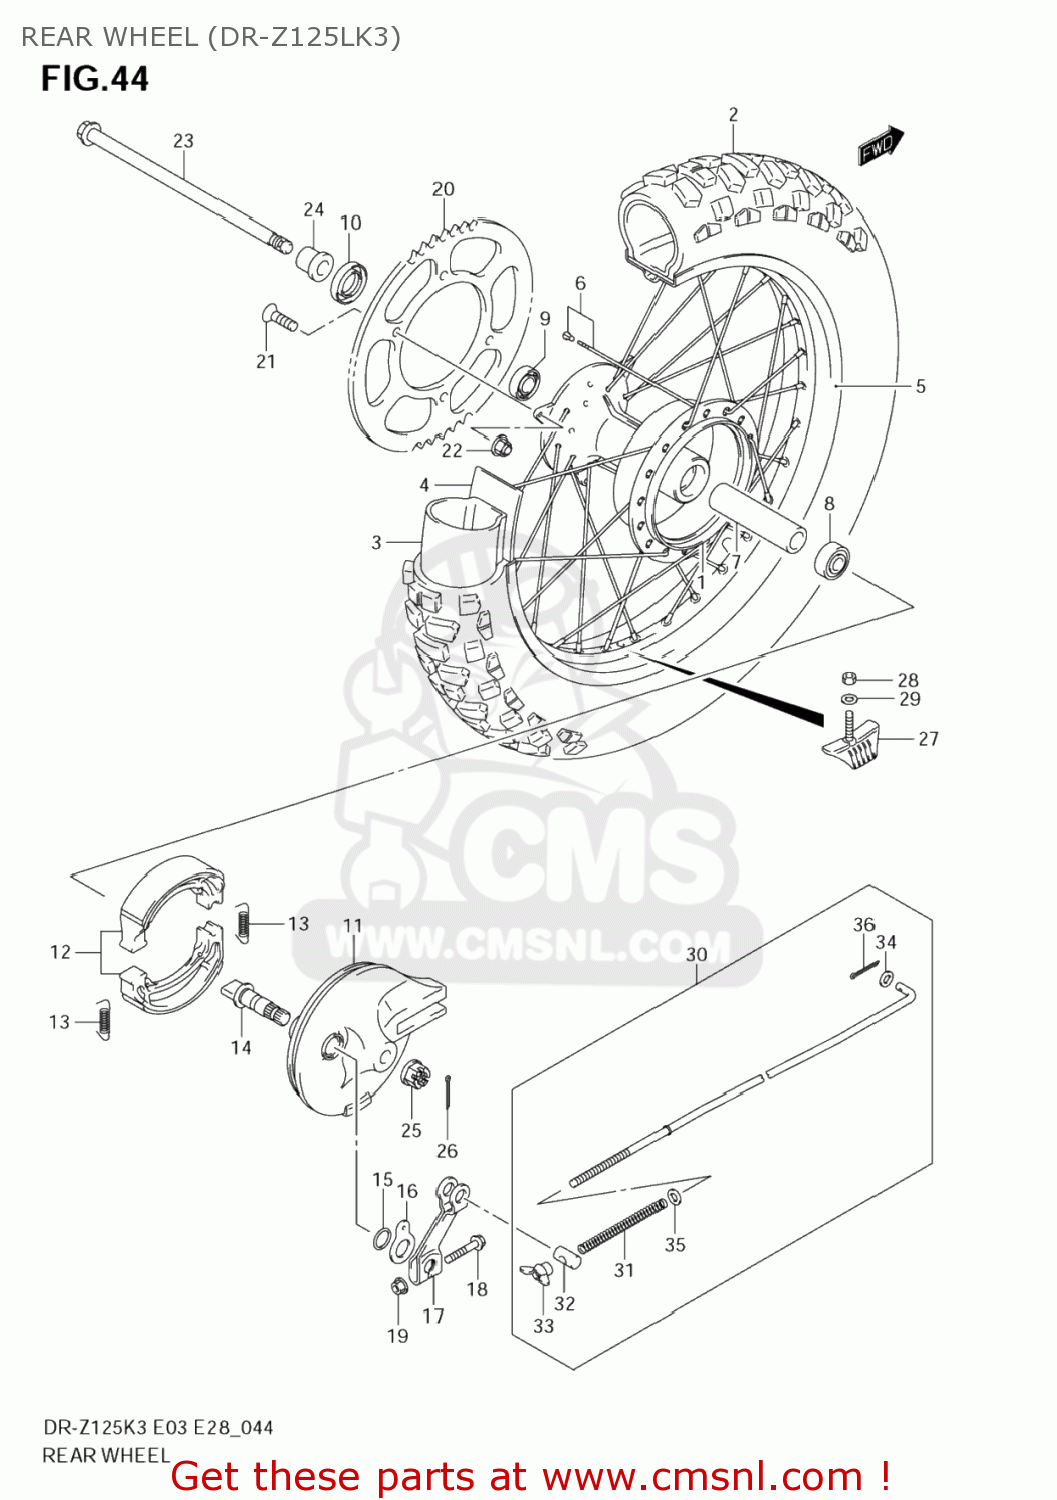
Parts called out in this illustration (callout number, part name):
1	HUB,RR WHEEL
2	TIRE,RR
3	TUBE ASSY,WHEEL INNER
4	PROTECTOR,WHL INR TUBE
5	RIM,RR WHEEL(16X1.60)
6	SPOKE SET,RR WHEEL
7	SPACER(12.5X19X105.5)
8	BEARING
9	BEARING
10	SEAL,OIL(20X37X7)
11	PANEL,RR BRAKE ANCHOR
12	SHOE SET,BRAKE (NAS)
13	SPRING
14	CAM,RR BRAKE
15	O RING(D:2.5,ID:13.8)
16	PLATE,BRAKE LINING INDICATOR
17	LEVER,RR BRAKE CAM
18	BOLT
19	NUT
20	SPROCKET,RR(57T-428)
21	BOLT(8X30.5)
22	NUT
23	AXLE,RR
24	SPACER,RR AXLE
25	NUT
26	PIN, COTTER
27	STOPPER,BEAD
28	NUT
29	WASHER
30	ROD ASSY,RR BRAKE
31	SPRING
32	PIN(11X18)
33	NUT
34	WASHER
35	WASHER
36	PIN 20X20
